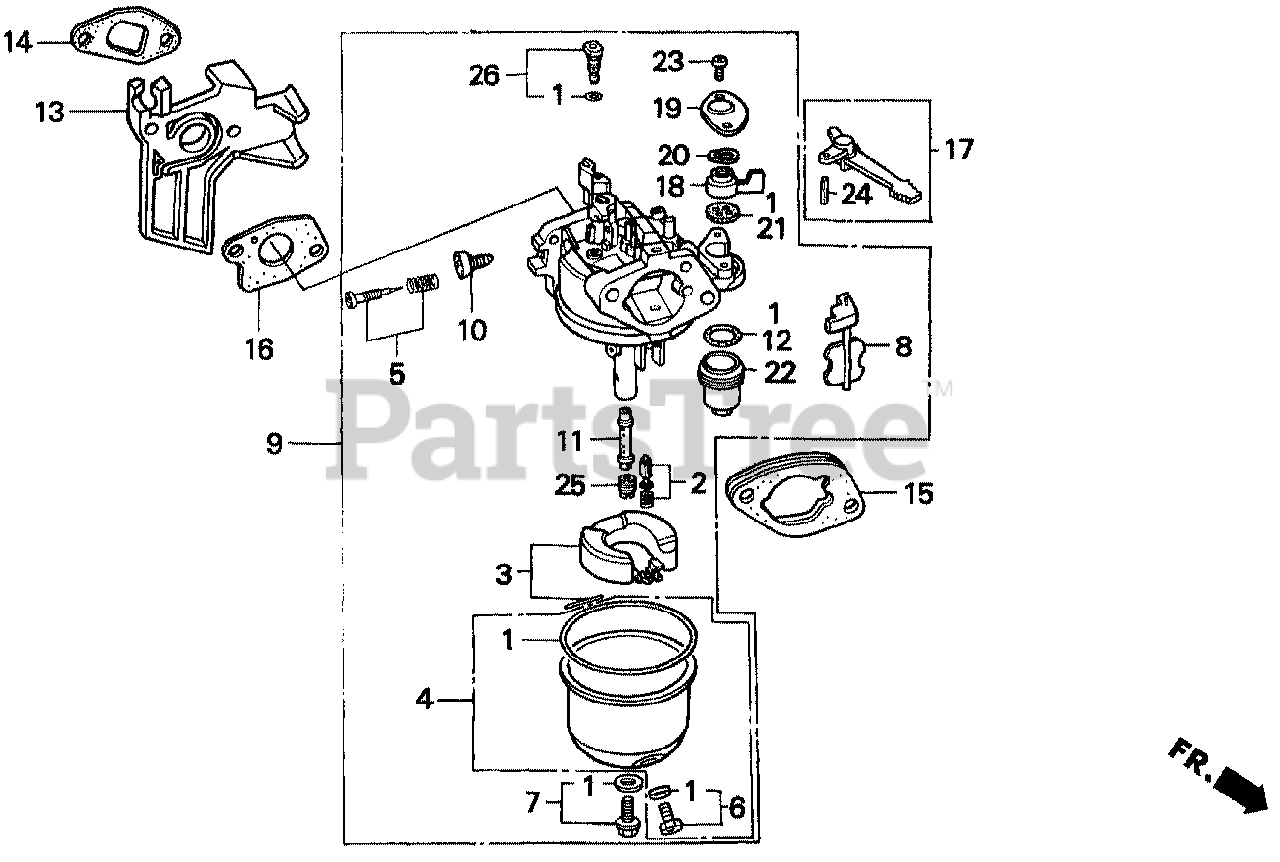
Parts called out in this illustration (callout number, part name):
1	GASKET SET
2	VALVE SET, FLOAT
3	FLOAT SET
4	CHAMBER SET, FLOAT
5	SCREW SET, PILOT
6	SCREW SET, DRAIN
7	SCREW SET B
8	CHOKE SET
9	CARBURETOR ASSY. (BE64C B)
10	SCREW, THROTTLE STOP
11	NOZZLE, MAIN
12	GASKET, FUEL STRAINER CUP
13	INSULATOR, CARBURETOR
14	GASKET, INSULATOR
15	SPACER, CARBURETOR
16	GASKET, CARBURETOR
17	LEVER, CHOKE (STD)
18	LEVER, VALVE
19	PLATE, LEVER SETTING
20	SPRING, VALVE LEVER
21	GASKET, VALVE
22	CUP, FUEL STRAINER
23	SCREW, PAN (3X6)
23	SCREW, PAN (3X8)
24	PIN, SPRING (2X12)
25	JET, MAIN (#72)
25	JET, MAIN (#75)
25	JET, MAIN (#70)
26	JET SET, PILOT (#45)
